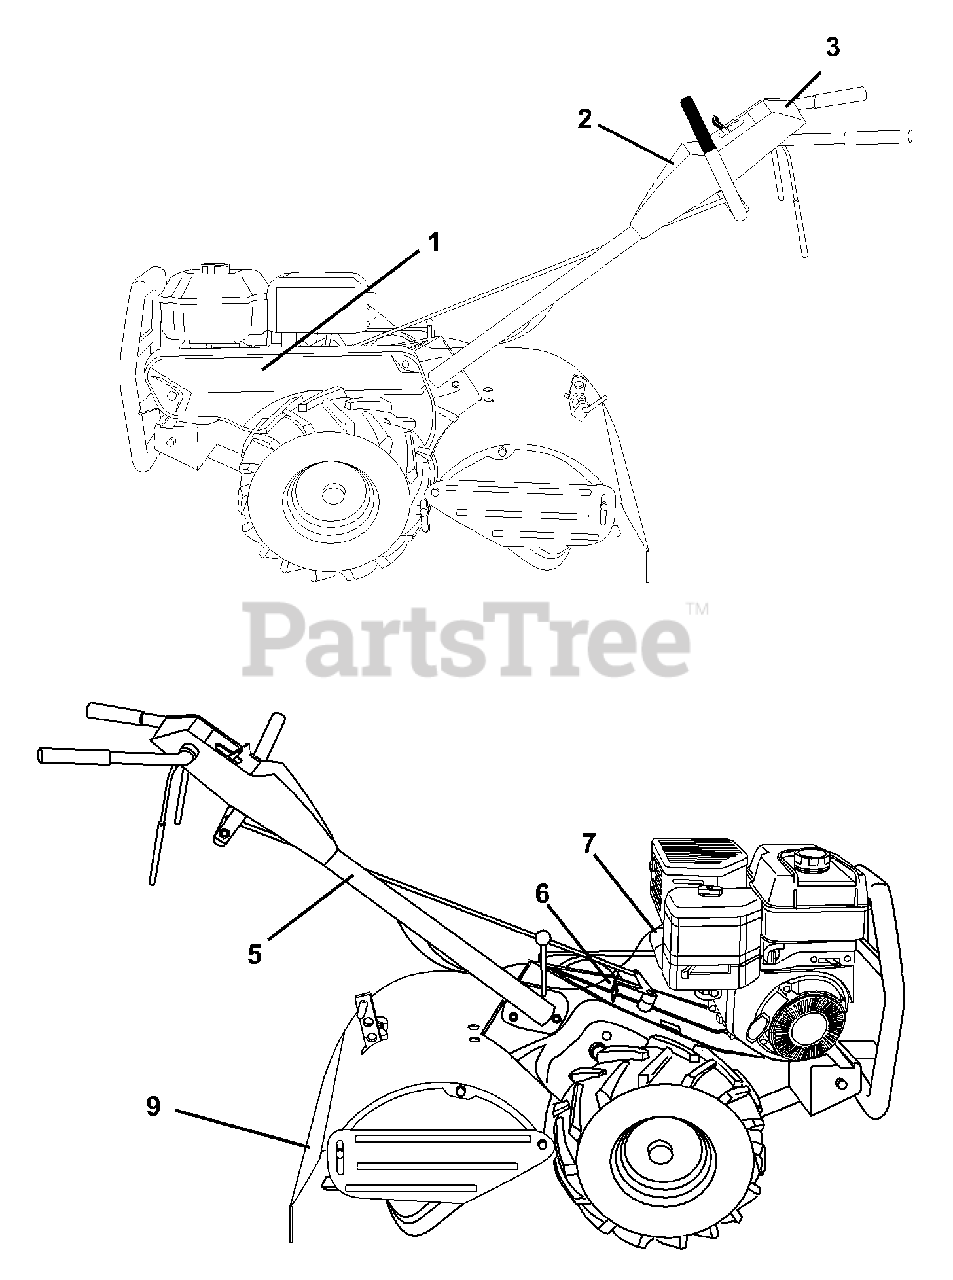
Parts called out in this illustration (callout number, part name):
1	Decal, Logo
2	Decal, Logo
3	Decal, Logo
5	Decal, Hand Placement
6	Decal, Shift Indicator
7	Decal, Caution
9	Decal, Warning, Rotating Tines
